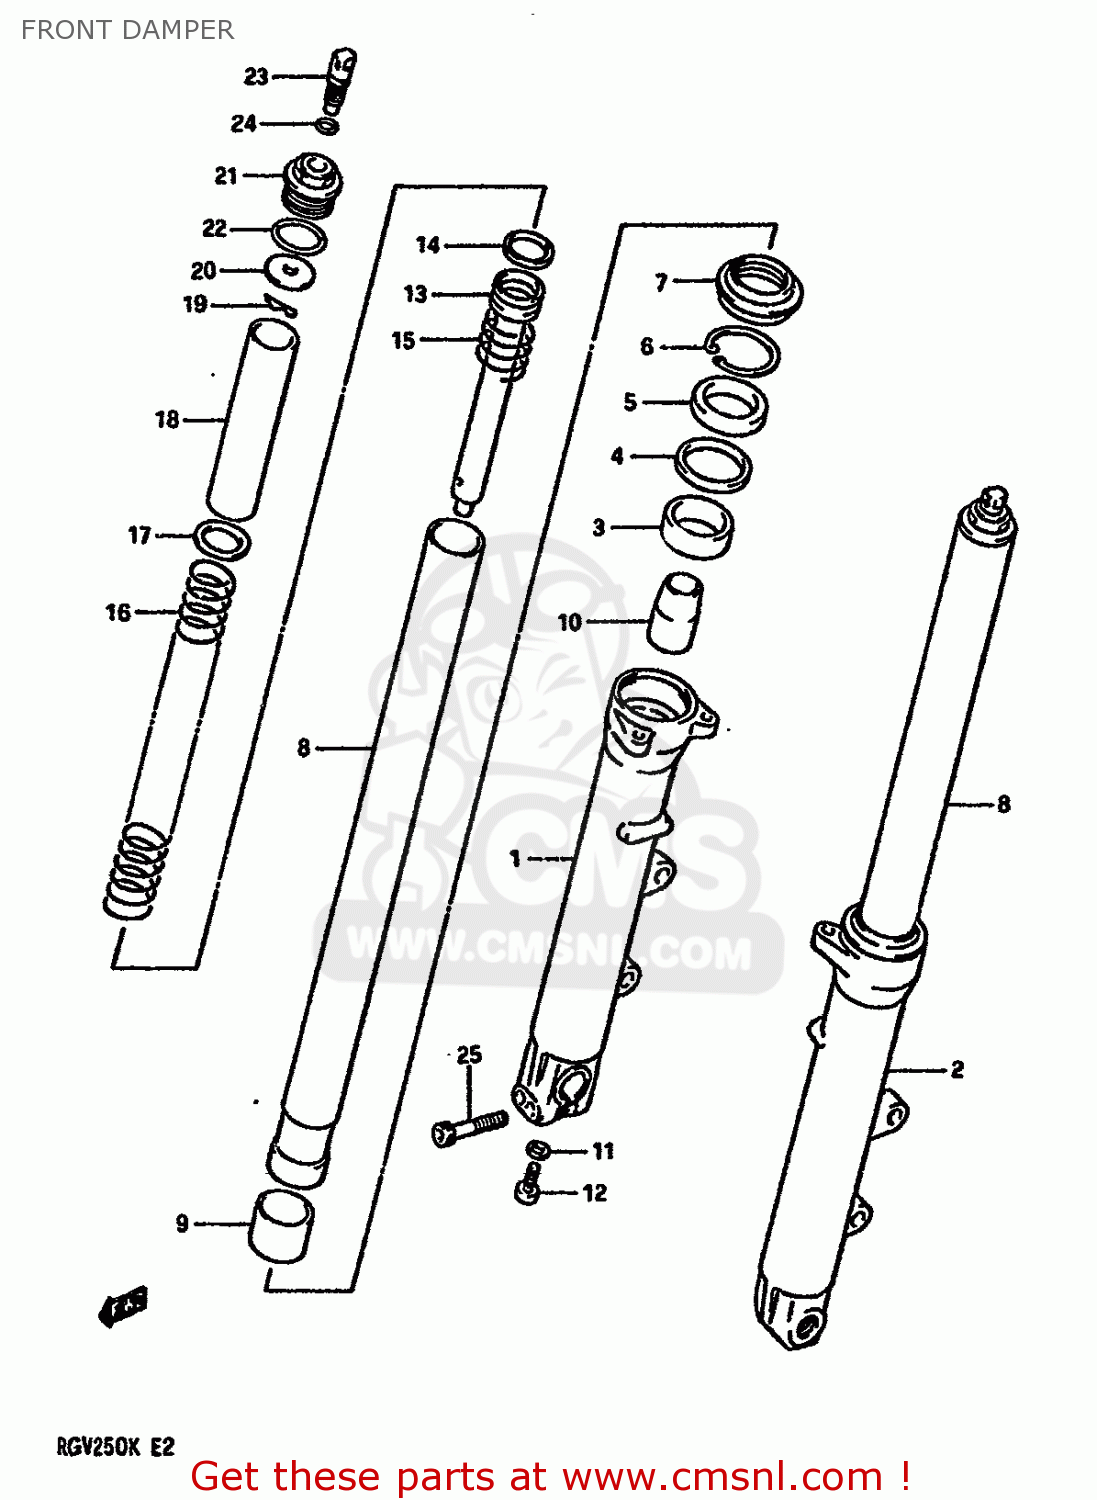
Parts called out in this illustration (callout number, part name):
1	TUBE,OUTER RH
2	TUBE,OUTER LH
3	BUSH,GUIDE
4	SPACER,SEAL
5	OIL SEAL,FRONT FORK
6	CIRCLIP,FORK OIL SEAL
7	BOOT
8	TUBE,INNER
9	BUSH,SLIDE
10	PIECE,OIL LOCK
11	GASKET (NAS)
12	BOLT(8X27)
13	CYLINDER
14	RING,PISTON
15	SPRING,REBOUND
16	SPRING
17	JOINT,SPRING
18	SPACER,SPRING
19	PIN,SEAT SPRING
20	SEAT,SPRING
21	BOLT,FORK
22	O RING
23	BOLT
24	RING
25	BOLT,AXLE HOLDER RH
